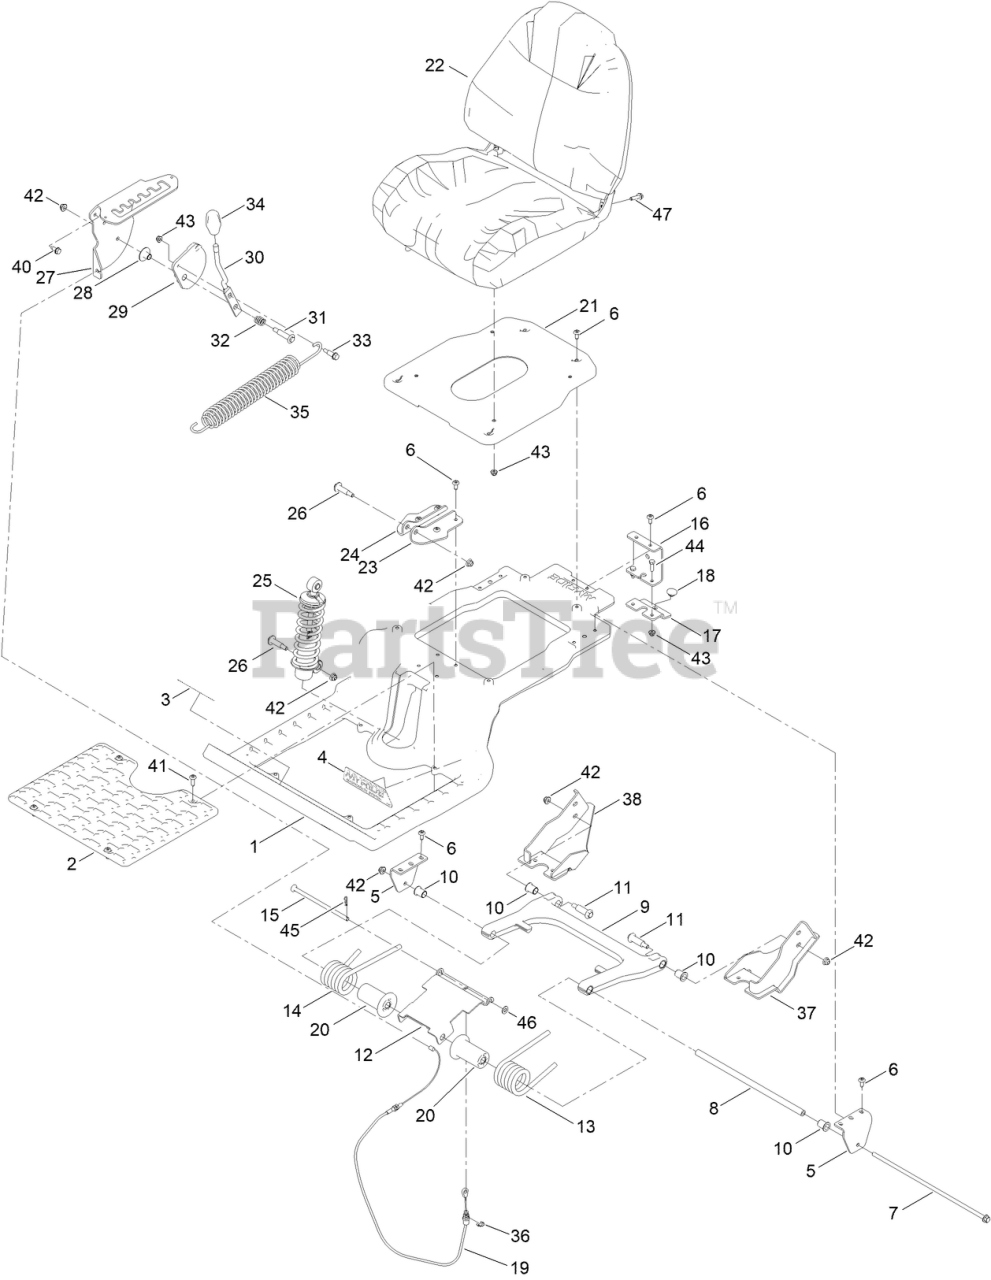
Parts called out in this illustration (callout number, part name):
1	PLATFORM, MYRIDE
2	PLATFORM, MYRIDE
3	DECAL - MYRIDE
4	DECAL - MYRIDE
5	BRACKET-MOUNT, SWING ARM
7	SCREW-HHF
8	TUBE-SPACER
9	ARM-SWING
10	BUSHING-FLANGE
11	BOLT-SHOULDER
12	PLATE-ADJUSTER
13	SPRING-TORSION, LH
14	SPRING-TORSION, RH
15	ROD-ADJUSTMENT
16	BRACKET-CABLE
17	BRACKET LOWER
18	BUMPER-SEAT
19	CABLE-ADJUSTMENT, MYRIDE
20	RETAINER-SPRING
21	PAN-SEAT
22	SEAT KING SK220 SEAT
23	BRACKET-SHOCK MOUNT, UPPER (LH)
24	BRACKET-SHOCK MOUNT, UPPER (RH)
25	SHOCK/SPRING ASM
26	BOLT-SHOULDER
27	BRACKET-MR GATE
28	BUSHING - FLANGE
29	PULLEY-CAM
30	LEVER-ADJUSTMENT, THREADED
31	BOLT-SHOULDER
32	SPRING-COMPRESSION
33	BOLT-SHOULDER, HHF
34	KNOB-MR
35	SPRING-EXTENSION
36	RING-RETAINING, EXTERNAL
37	MOUNT-MR SWING ARM, LH
38	MOUNT-MR SWING ARM, RH
40	SCREW-HWHTF
41	SCREW-SPCL
42	NUT-HF, NI
43	NUT-HF
44	SCREW-HH
45	PIN-HAIR
46	WASHER-FLAT
